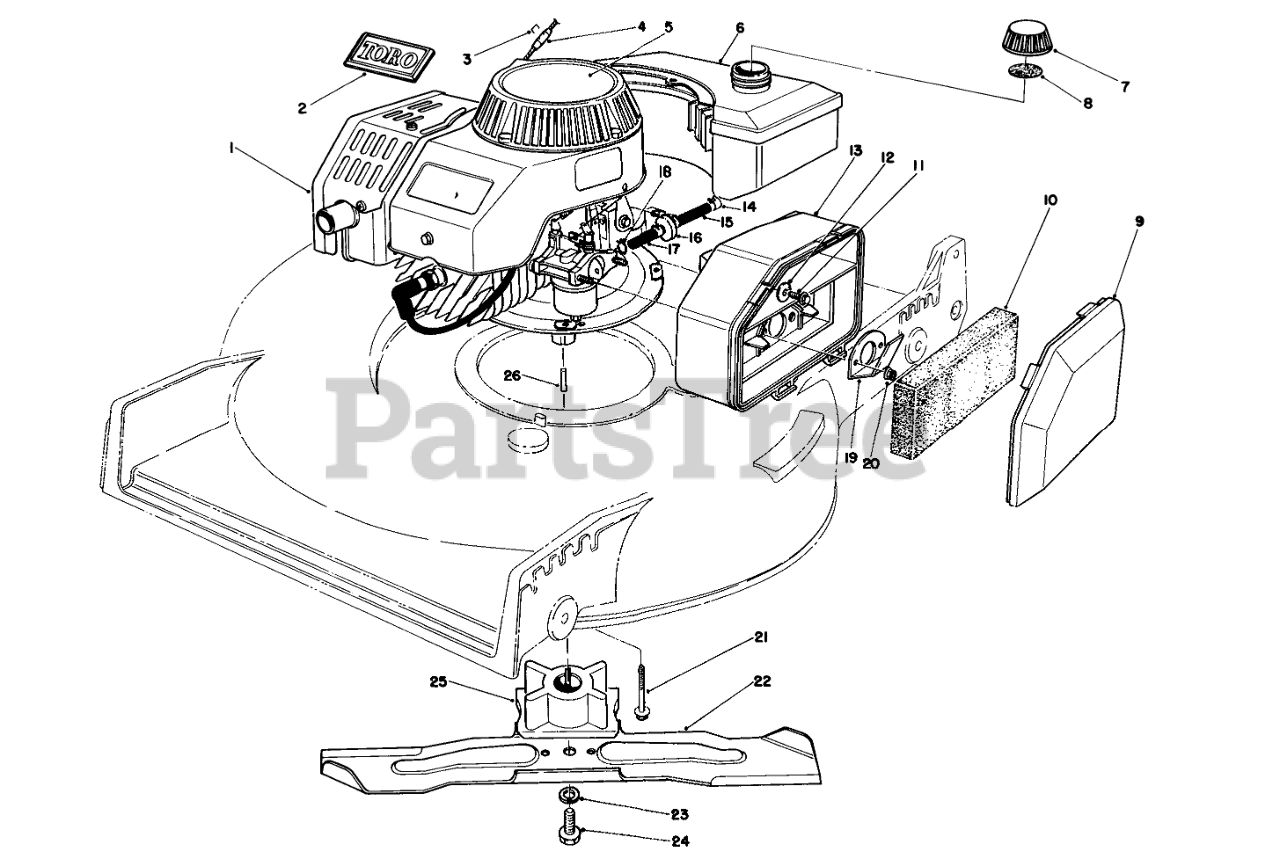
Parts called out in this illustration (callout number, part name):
1	Engine
2	TORO LOGO PLT
3	Staple
4	STOP-ROPE
5	DECAL
6	Gas Tank Assembly
7	Gas Cap Assembly (Incl. Ref. #8)
8	GAS CAP GASKET
9	AIR CLEANER COVER
10	FILTER
11	SCREW-HH
12	WASHER-FLAT
13	AIR CLEANER
14	CLAMP-FUEL LINE
15	HOSE-FUEL
16	FILTER-FUEL
17	HOSE-FUEL
18	GASKET-AIR CLEANER
19	SPIT BACK DEFLECTOR
20	NUT-LOCK
21	SCREW-HHF
22	BLADE-21in
23	WASHER-LOCK
24	SCREW-BLADE
25	Retainer Blade
26	KEY-SQUARE
